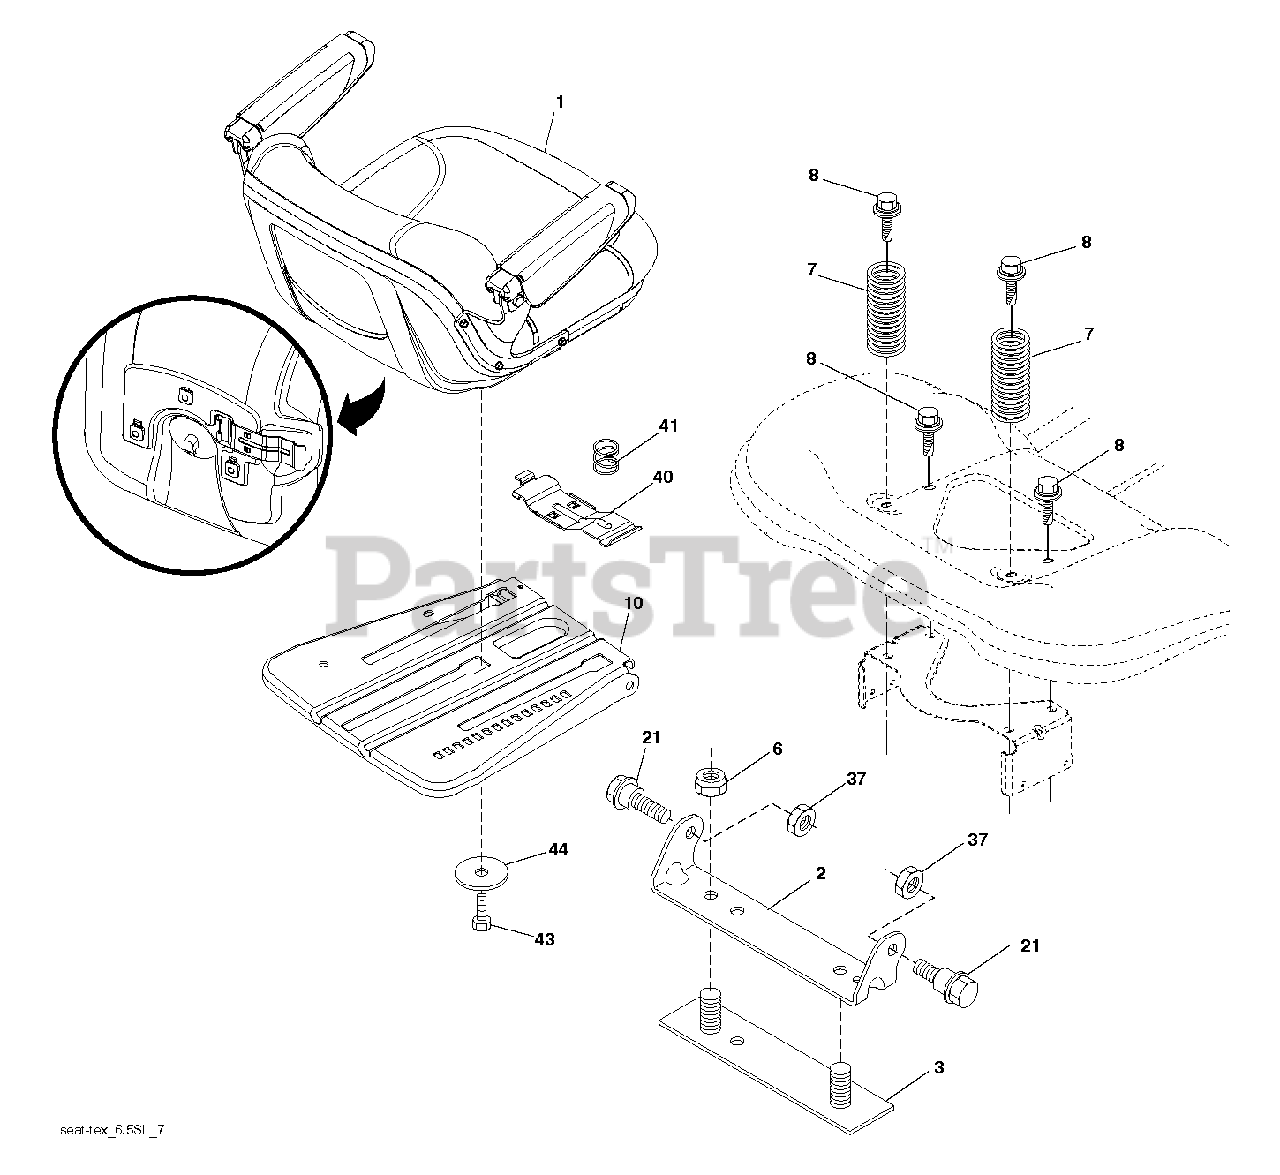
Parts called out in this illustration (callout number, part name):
1	SEAT.TH154.GREY.HUS.ARMREST
2	BRKT.PIVOT.FENDER
3	STRAP
6	NUT
7	SPRING.COMPRESSION.SEAT.BLACK
8	BOLT, 5/16-18 X 1 3/4
10	PAN.ASM.SEAT.3PT
21	BOLT.5/16-18X5/8.SHOULDER
37	NUT.71038.31-18.HEX.NYLOCK
40	HANDLE.SLIDE.SEAT.TEX.BLACK
41	SPRING.LATCH.SEAT.TEX
44	WASHER 13/32 X 2-3/8 X 12GA
